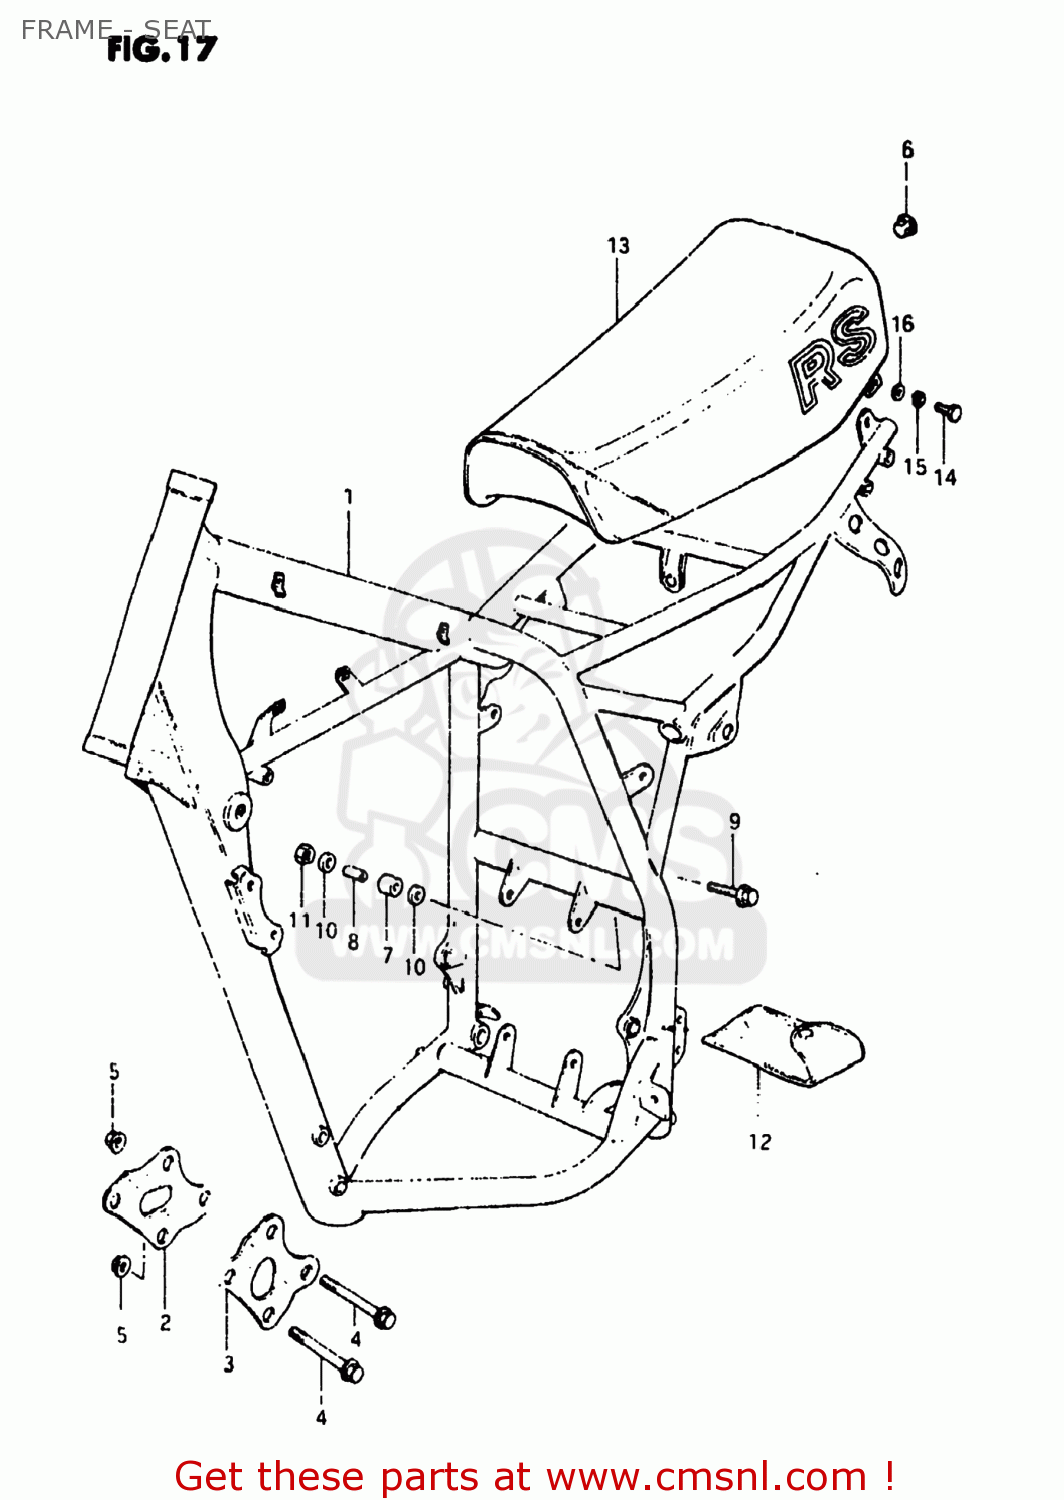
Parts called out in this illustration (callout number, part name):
1	FRAME
2	PLATE,ENGINE MOUNTING
3	PLATE,ENGINE MOUNTING
4	BOLT
5	NUT
6	PLUG(OD:19)
7	ROLLER,CHAIN CONTROL
8	SPACER,CHAIN LENGTH ROLLER
9	BOLT(8X45)
10	WASHER
11	NUT
12	TOOL SET
13	SEAT ASSEMBLY
14	BOLT
15	LOCK WASHER
16	WASHER
